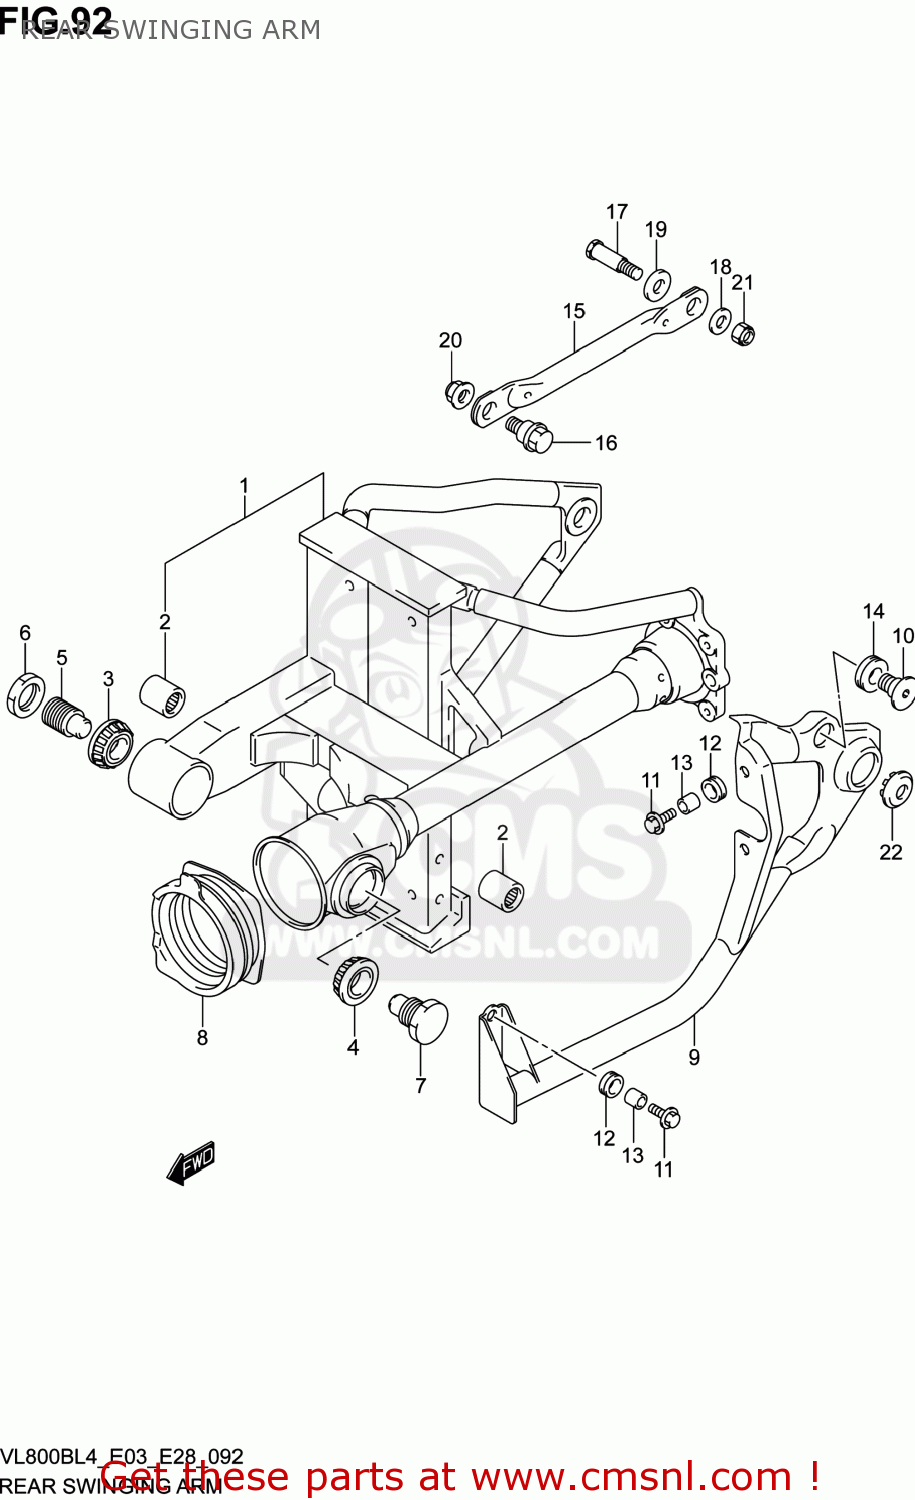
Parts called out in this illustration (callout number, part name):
1	SWINGINGARM SET,RR
2	BEARING(17X24X25)
3	BEARING(17X40X13.25)
4	BEARING(17X40X13.25)
5	BOLT,RR SWGARM PIVOT
6	NUT
7	BOLT,SWINGINGARM PIVOT,L
8	BOOT,PROPELLER SHAFT
9	COVER,RR SWINGINGARM,L(BLACK)
10	BOLT,COVER RR
11	BOLT(6X20)
12	CUSHION
13	SPACER(6.5X10X9.4)
14	CUSHION
15	TORQUE LINK,RR
16	BOLT(10X22)
17	BOLT(10X41)
18	WASHER(10X20X2.3)
19	CUSHION
20	NUT
21	NUT
22	CAP,FRAME PIVOT
